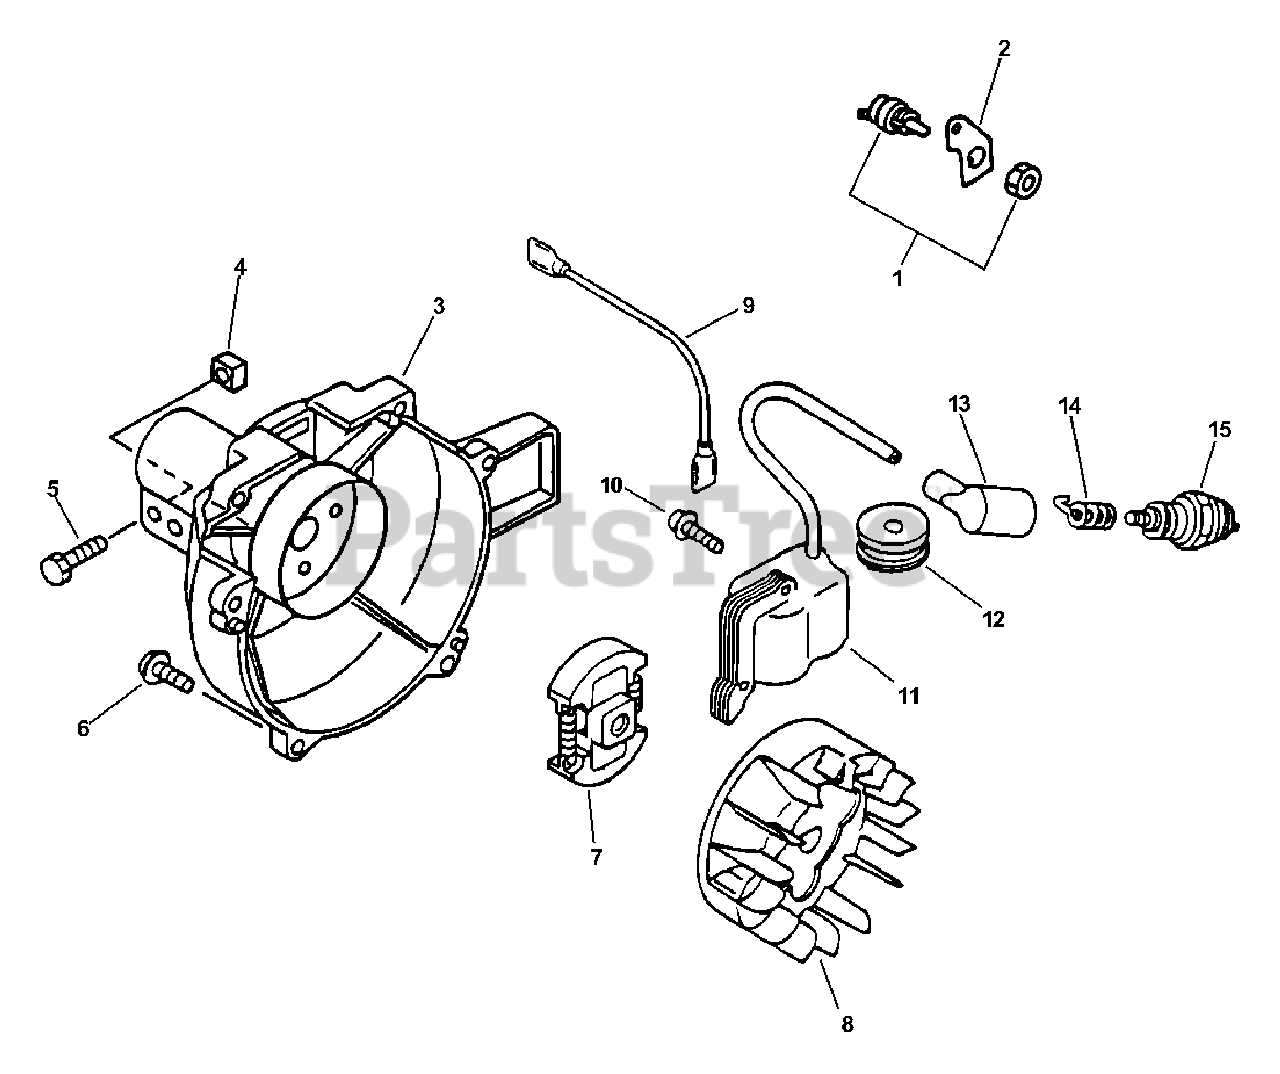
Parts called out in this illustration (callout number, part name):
1	IGNITION SWITCH ASSY
2	BRACKET, SWITCH
3	FAN CASE ASSY
4	NUT - 5 -- SQUARE
5	BOLT - 5X28
6	SCREW - 4X18
7	CLUTCH ASSY
8	FLYWHEEL
9	LEAD - IGNITION
10	SCREW - 4X22
11	COIL, IGNITION
12	GROMMET
13	CAP, SPARK PLUG
14	TERMINAL, SPARK PLUG CAP
15	SPARK PLUG -- BPM-7A
15	SPARK PLUG -- RCJ-7Y
